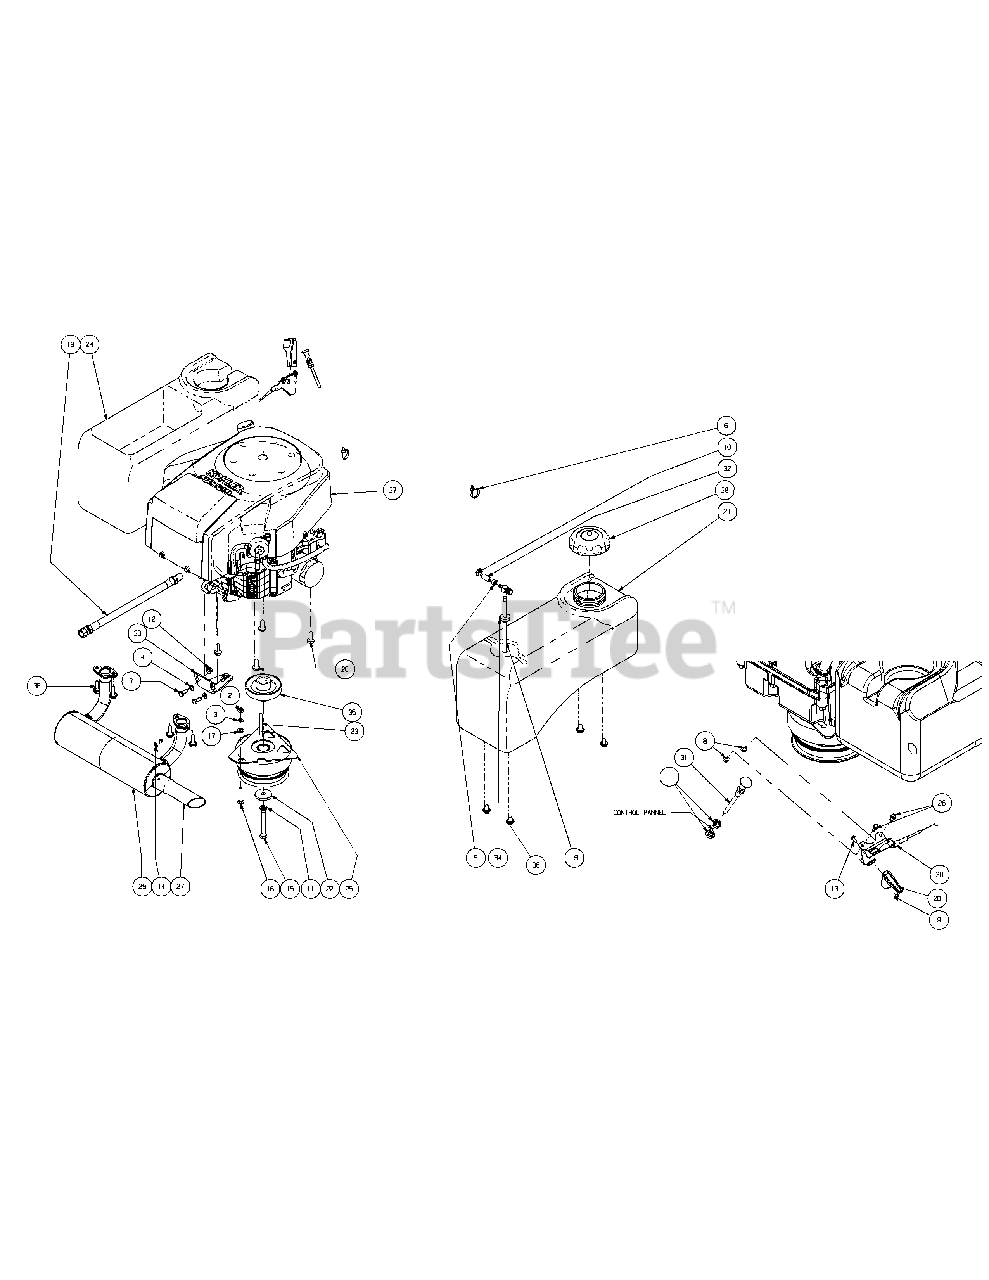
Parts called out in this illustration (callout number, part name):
1	Hex Jam Nut, 3/8-24
2	Hex Nut, 5/16-18
3	Lock Washer, 5/16
4	Flat Washer, 5/16
5	Clamp, Union
6	Cable Tie, 3/16 x .05 x 7.4
7	Hex Cap Screw, 5/16-18 x .75
8	Lock Nut, Nylon Insert, 10-32
9	Nut, w/ Star Washer
10	Hose Clamp, 1/4-5/8, SS
11	Lock Washer, 7/16
12	Lock Nut, Hex Flange, 5/16-18
13	Machine Screw, 8-32 x .375
14	Screw, 8-32 x .375, Hex Washer
15	Hex Cap Screw, 7/16-20 x 3.0
16	Carriage Bolt, 5/16-18 x 1.75
17	Washer, 3/8 x .738 x .063
18	Fuel Pickup Fitting
19	Oil Drain Extension Hose
20	Throttle Control Knob
21	Fuel Tank
22	Flat Washer, 7/16 ID x 1.75 OD x .250
23	Key, 1/4 x 1/4 x 2.75
24	Utility Bin
25	Ogura DX11 Electric Clutch
26	Screw, #10-32 x 0.500
27	Exhaust Pipe
28	Self Tapping Screw, 3/8-16 x 0.875
29	Kohler Muffler
30	Throttle Control Cable
31	Choke Cable
32	Hose, 1/4" Fuel Line
34	Fuel Tank Groment
35	Transmission Drive Pulley
36	Hex Head Cap Screw, 3/8-16 x 1.00, Flange Whiz
37	23HP Kohler Engine
38	Hex Head Cap Screw, 5/16-18 x 1.00, Flange Whiz
39	Fuel Cap
